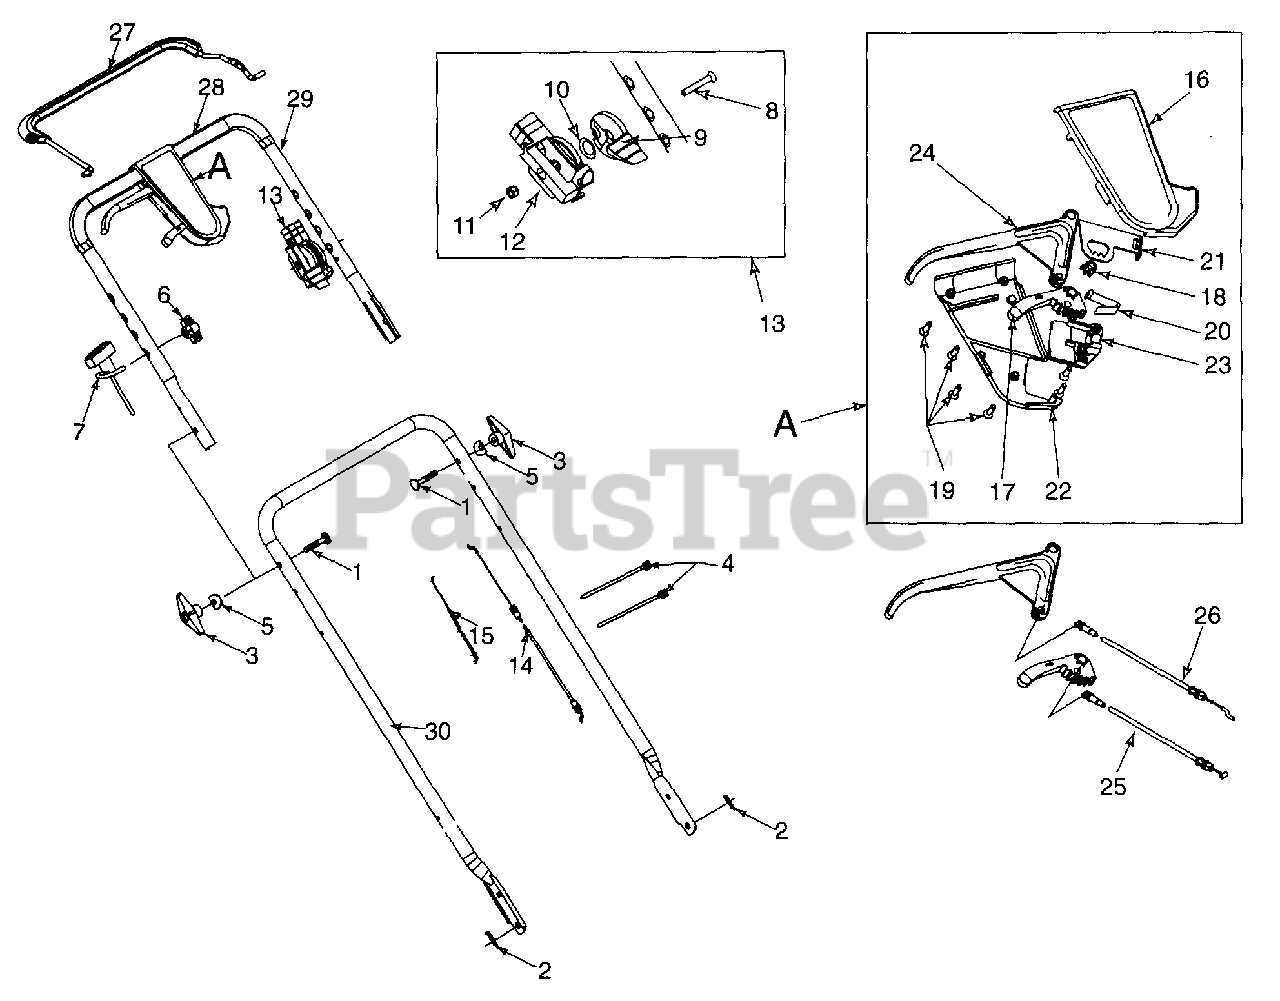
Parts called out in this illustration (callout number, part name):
1	Bolt Curv. Carr. 5/16-18 x 2.0
2	Cotter Pin .072 x 1.12 Lg.
3	Knob Ass'y Wingnut 5/16-18
4	Strap 4.3 Lg.
5	Wash. Sad. .320 ID x .830 O.D.
6	Knob Handle ERS - 1/4-20
7	Rope Guide Eyebolt
8	Screw 1/4-20 x 1.81
9	Throttle Lever
10	Spring Wash. Curved
11	Nut 1/4-20 Top Locknut Insert
12	Housing, Throttle
13	Throttle Control
14	Control Cable 47" Lg.
15	Cable Throttle 60" Lg.
16	Upper Control Housing
17	6 Speed Shift Lever
18	Gear Insert
19	CSunk Tap Scr #10 x .75 L
20	Shift Lever Spring
21	6 Spd. Rack Cable Brkt.
22	Lower Control Housing
23	Cable Mounting Cap
24	Control Lever
25	6 Spd. Cable
26	S.P. Cable
27	Control Handle
28	Foam Grip
